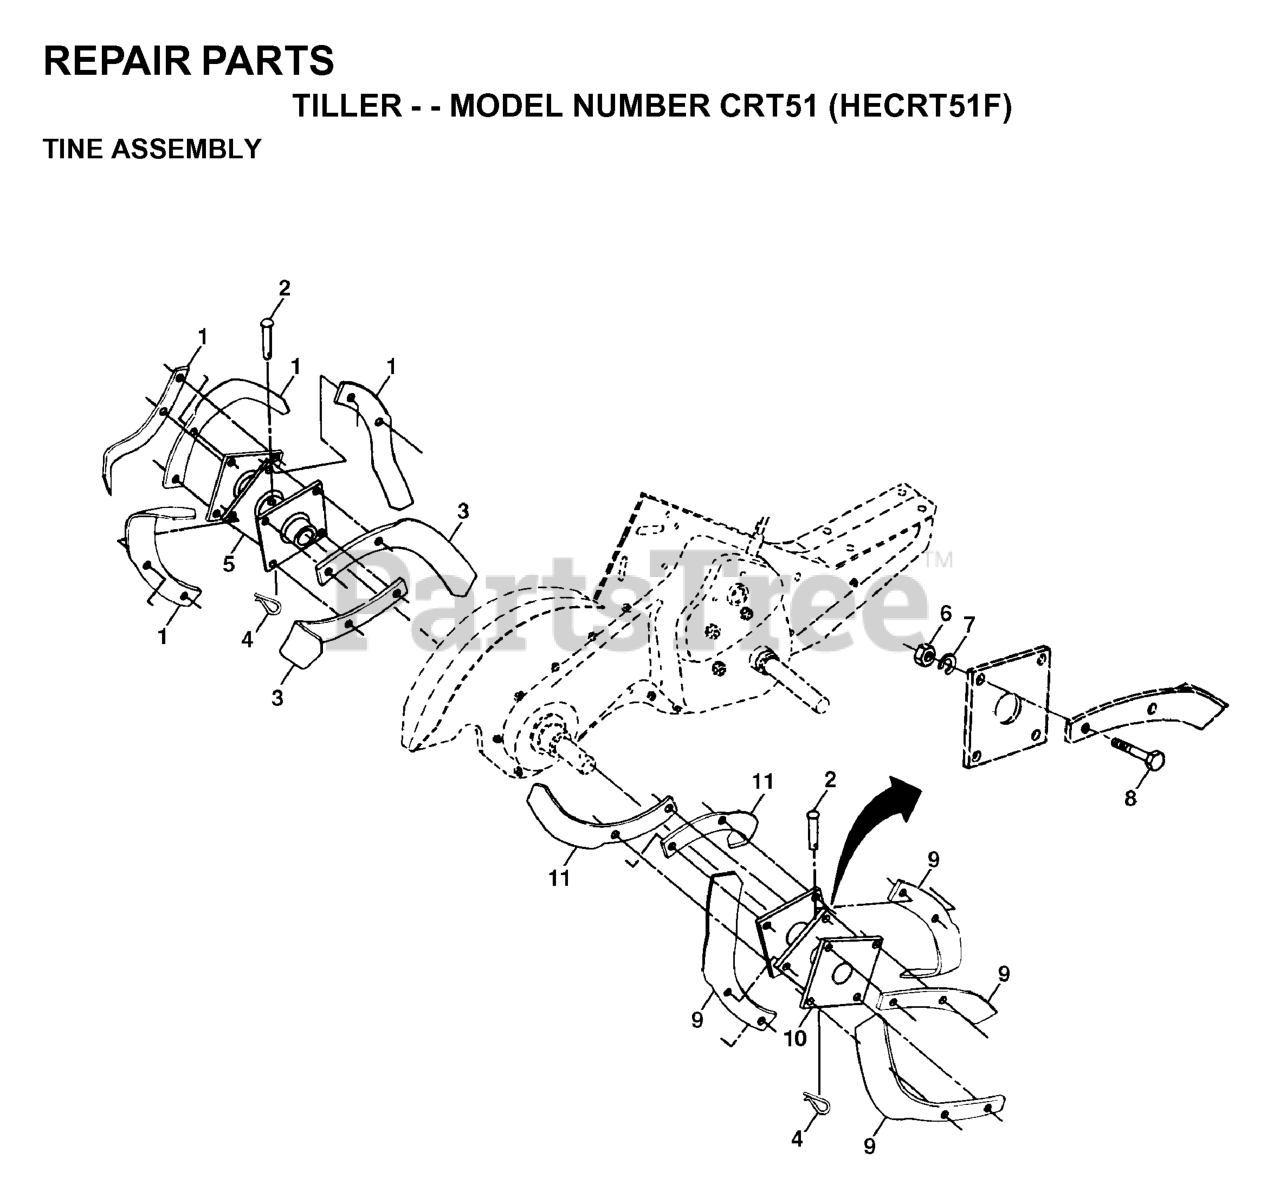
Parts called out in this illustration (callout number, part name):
1	TINE TI
2	PIN RETAINING SCREW
3	TINE.LH.12"(72L)
4	SPRING RETAINER
5	HUB.&.PLATE.ASM.LH
6	NUT
7	WASHER, LOCK 3/8
8	BOLT.HEX.001X20.37-24X1.ZINC
9	TINE TI
10	HUB & PLATE ASM RH
11	TINE.RH.12"(72R)
